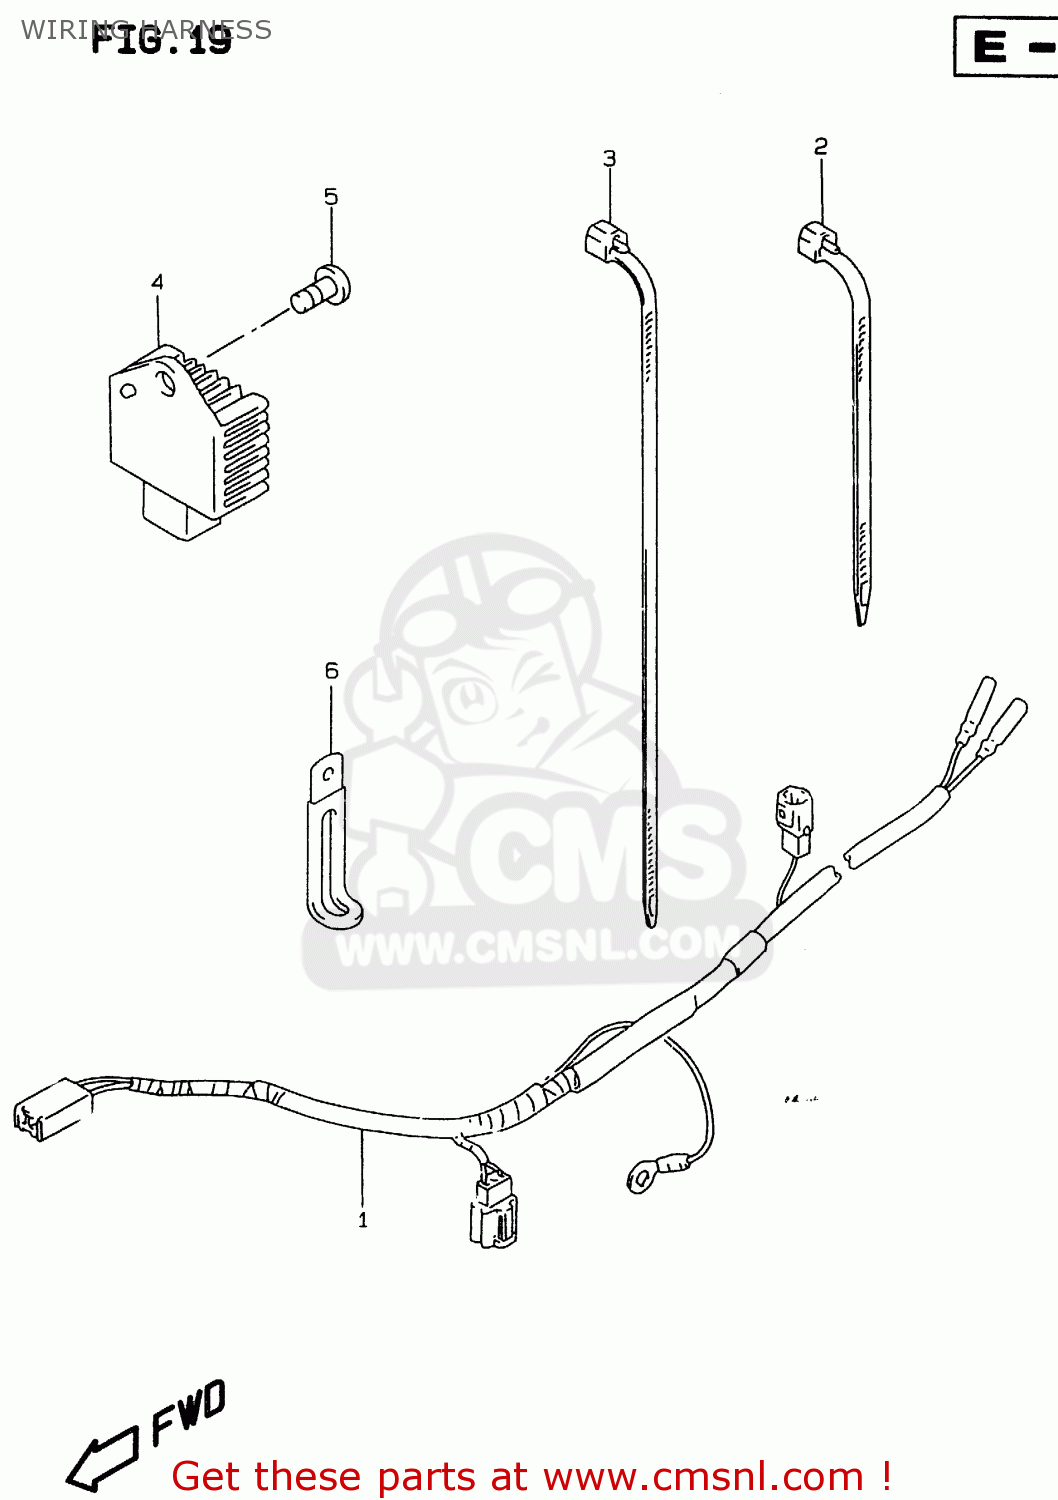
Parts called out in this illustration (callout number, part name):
1	HARNESS,WIRING
2	CLAMP(L:95)
3	CLAMP(L:235)
4	REGULATOR ASSY
5	SCREW
6	CLAMP(L:65)
